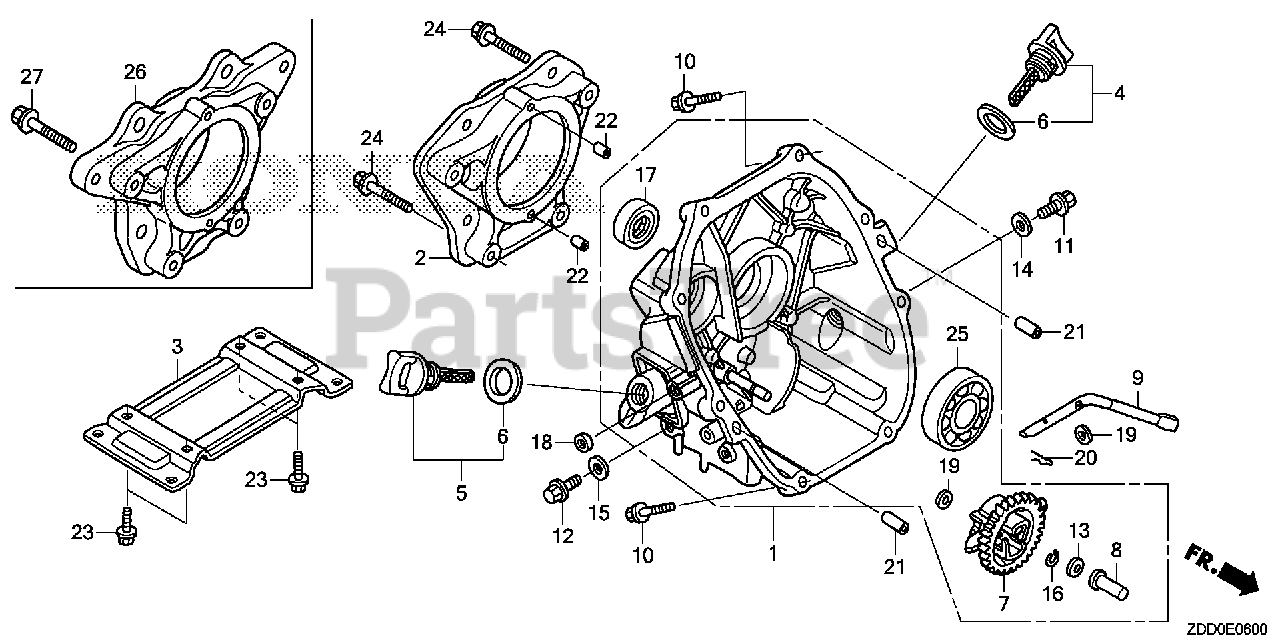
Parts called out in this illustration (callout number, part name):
1	COVER ASSY., CRANKCASE
3	BED, ENGINE
4	CAP ASSY., OIL FILLER
5	CAP ASSY., OIL FILLER
6	GASKET, OIL FILLER CAP
7	GOVERNOR ASSY.
8	SLIDER, GOVERNOR
9	SHAFT, GOVERNOR ARM
10	BOLT, FLANGE (6X25) Use up to Engine SN 2056819.
11	BOLT, DRAIN PLUG
12	BOLT, DRAIN PLUG
13	WASHER, THRUST (6MM)
14	WASHER, DRAIN PLUG (10.2MM)
15	WASHER, DRAIN PLUG (10.2MM)
16	CLIP, GOVERNOR HOLDER
17	OIL SEAL (20X32X6)
19	WASHER, PLAIN (6MM)
20	PIN, LOCK (8MM)
21	PIN, DOWEL (8X20)
23	BOLT, FLANGE (8X25)
25	BEARING, RADIAL BALL (6204)
